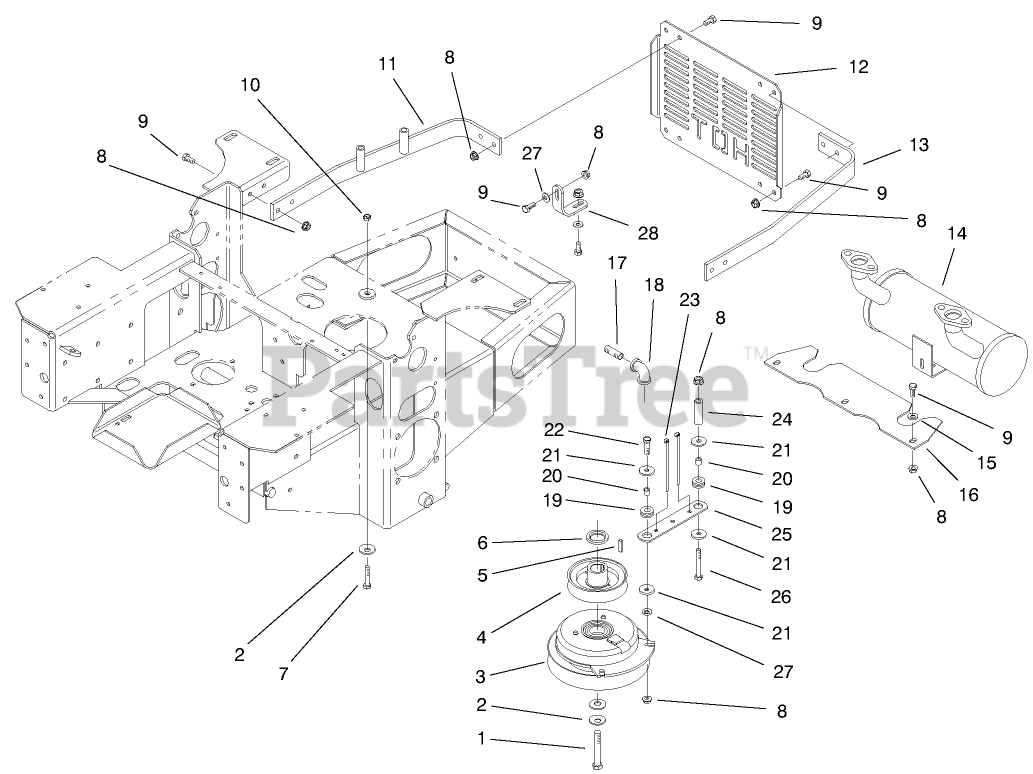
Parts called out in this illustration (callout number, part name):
1	SCREW-HH
2	Disc-Spring
3	Clutch
4	Sheave-Pump Drive
5	Key
6	Spacer-Crankshaft
7	SCREW-HH
8	NUT-HF
9	SCREW-HH
10	NUT-HF
11	Strap-Guard, Engine
12	Shield-Guard, Engine
13	Strap-Guard, Engine
14	Muffler
15	WASHER-PLAIN
16	Shield-Heat
17	Pipe Nipple
18	Elbow
19	Grommet
20	Spacer
21	Washer
22	SCREW-HH
23	Tie-Plastic
24	Bushing-Mount, Seat
25	Strap
26	SCREW-HH
27	WASHER-FLAT
28	Bracket-Muffler
29	Engine-20hp Kohler
